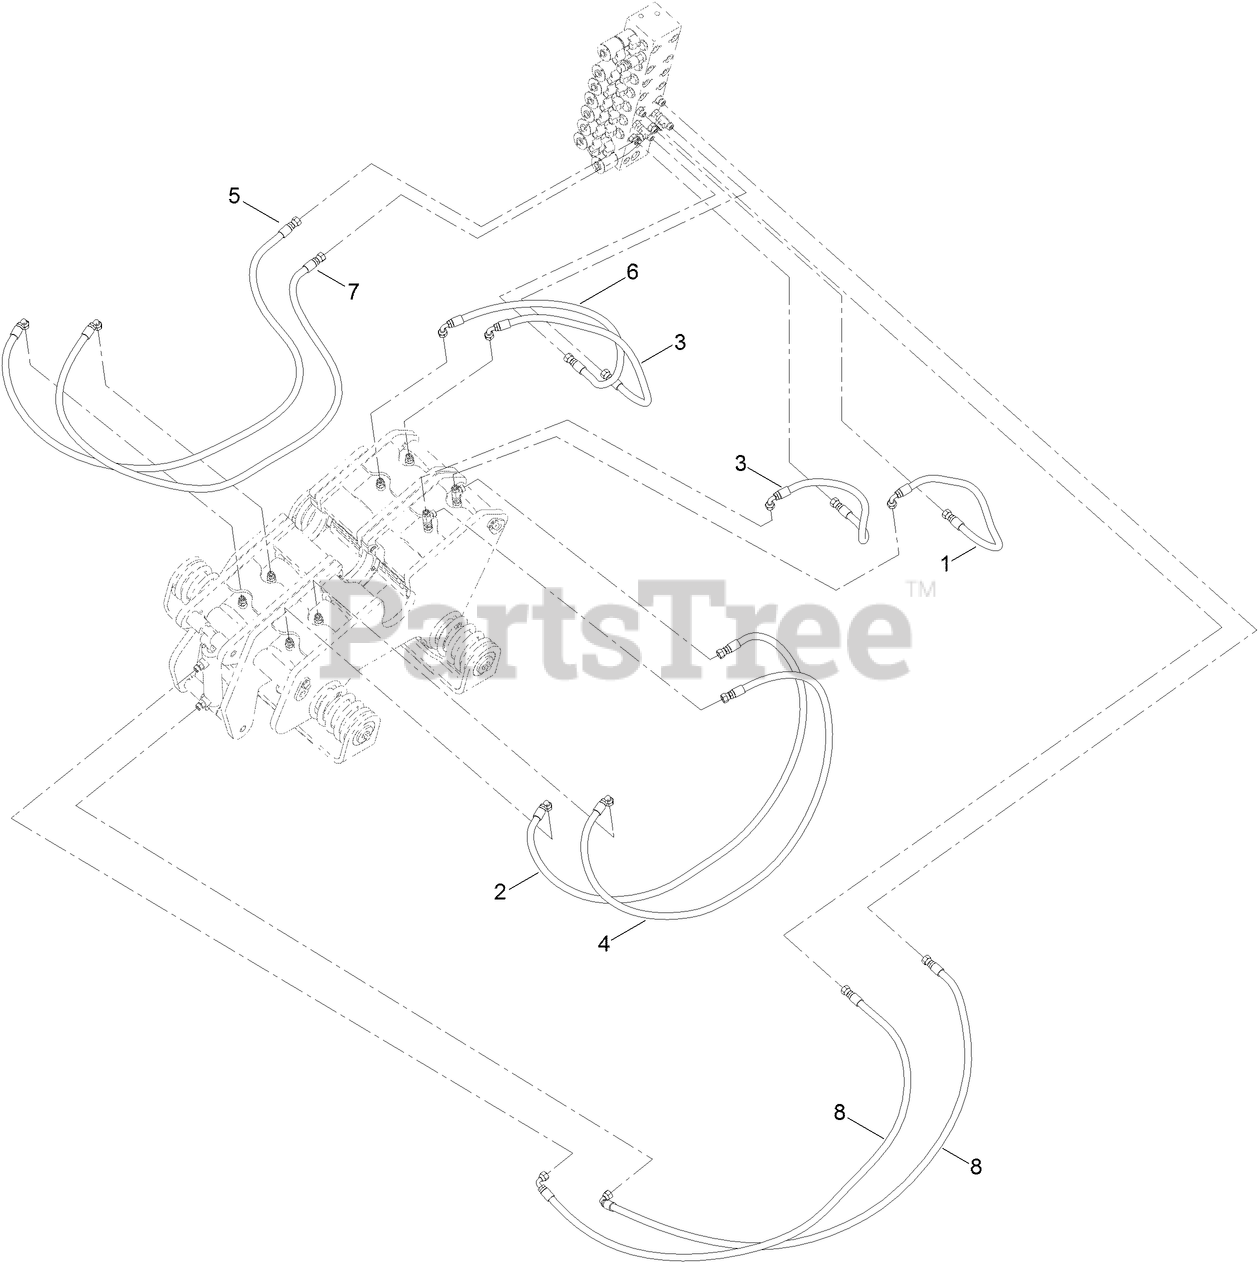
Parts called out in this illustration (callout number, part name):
1	HOSE ASM-HYD
2	HOSE ASM-HYD
3	HOSE ASM-HYD
4	HOSE ASM-HYD
5	HOSE ASM-HYD
6	HOSE ASM-HYD
7	HOSE ASM-HYD
8	HOSE ASM-HYD
